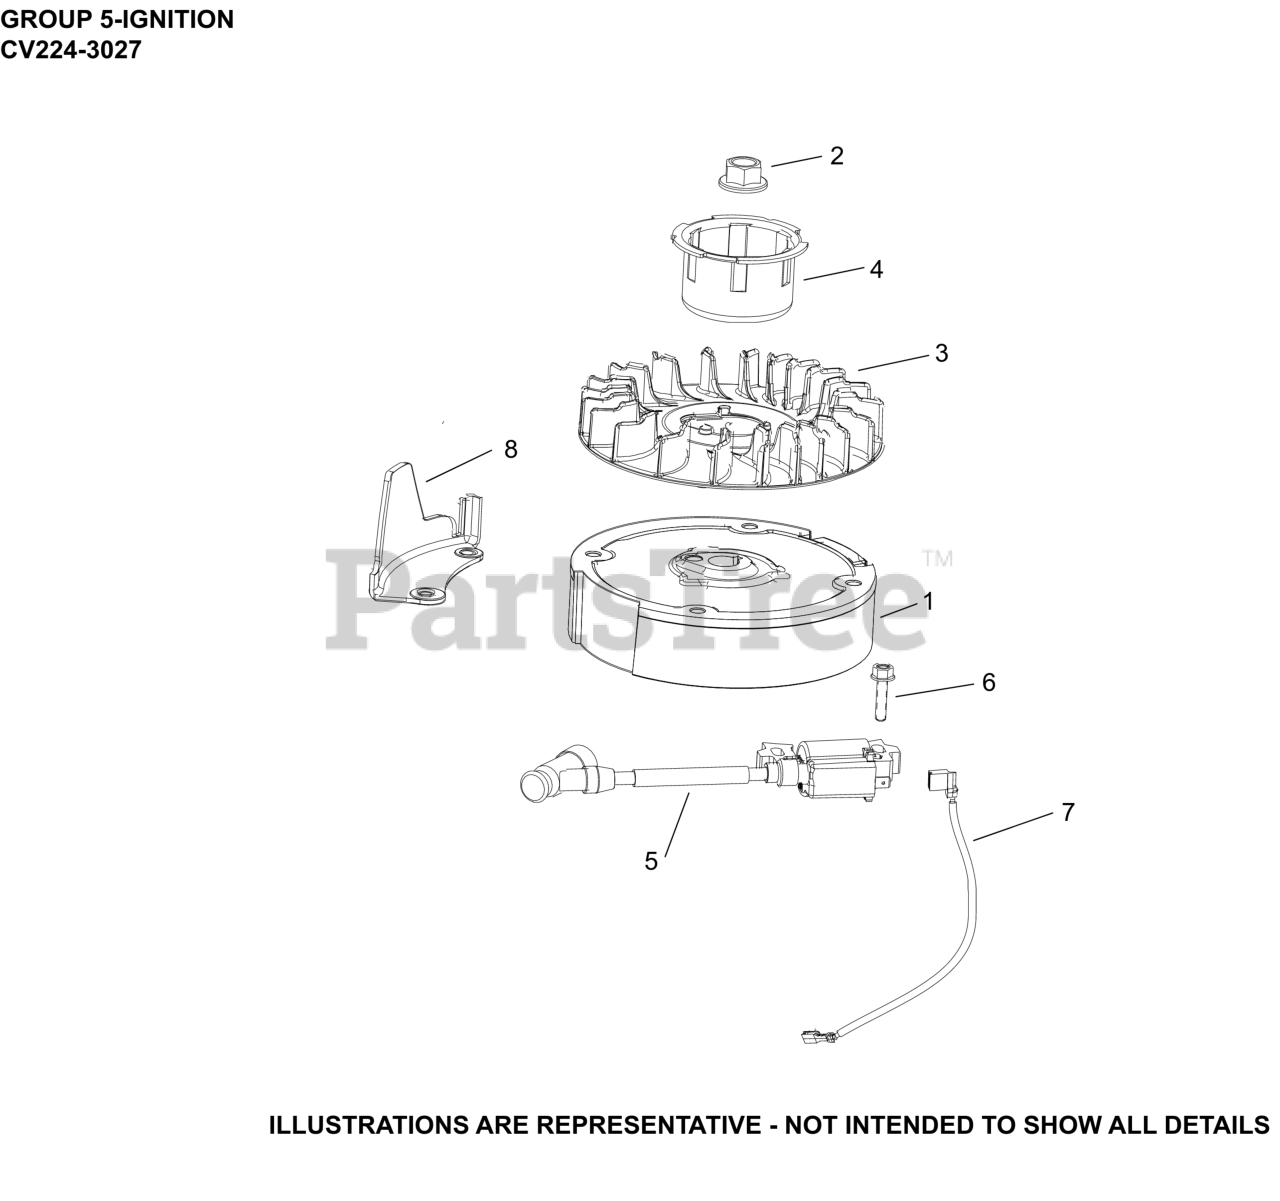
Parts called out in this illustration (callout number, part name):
1	FLYWHEEL (CAST IRON)
2	NUT, FLYWHEEL (W/SERRATIONS)
3	FAN, FLYWHEEL
4	CUP, STARTER DRIVE
5	MODULE IGN (#1458416S)
6	SCREW, M6 X 25-(#25086436S)
8	GUARD, FINGER
